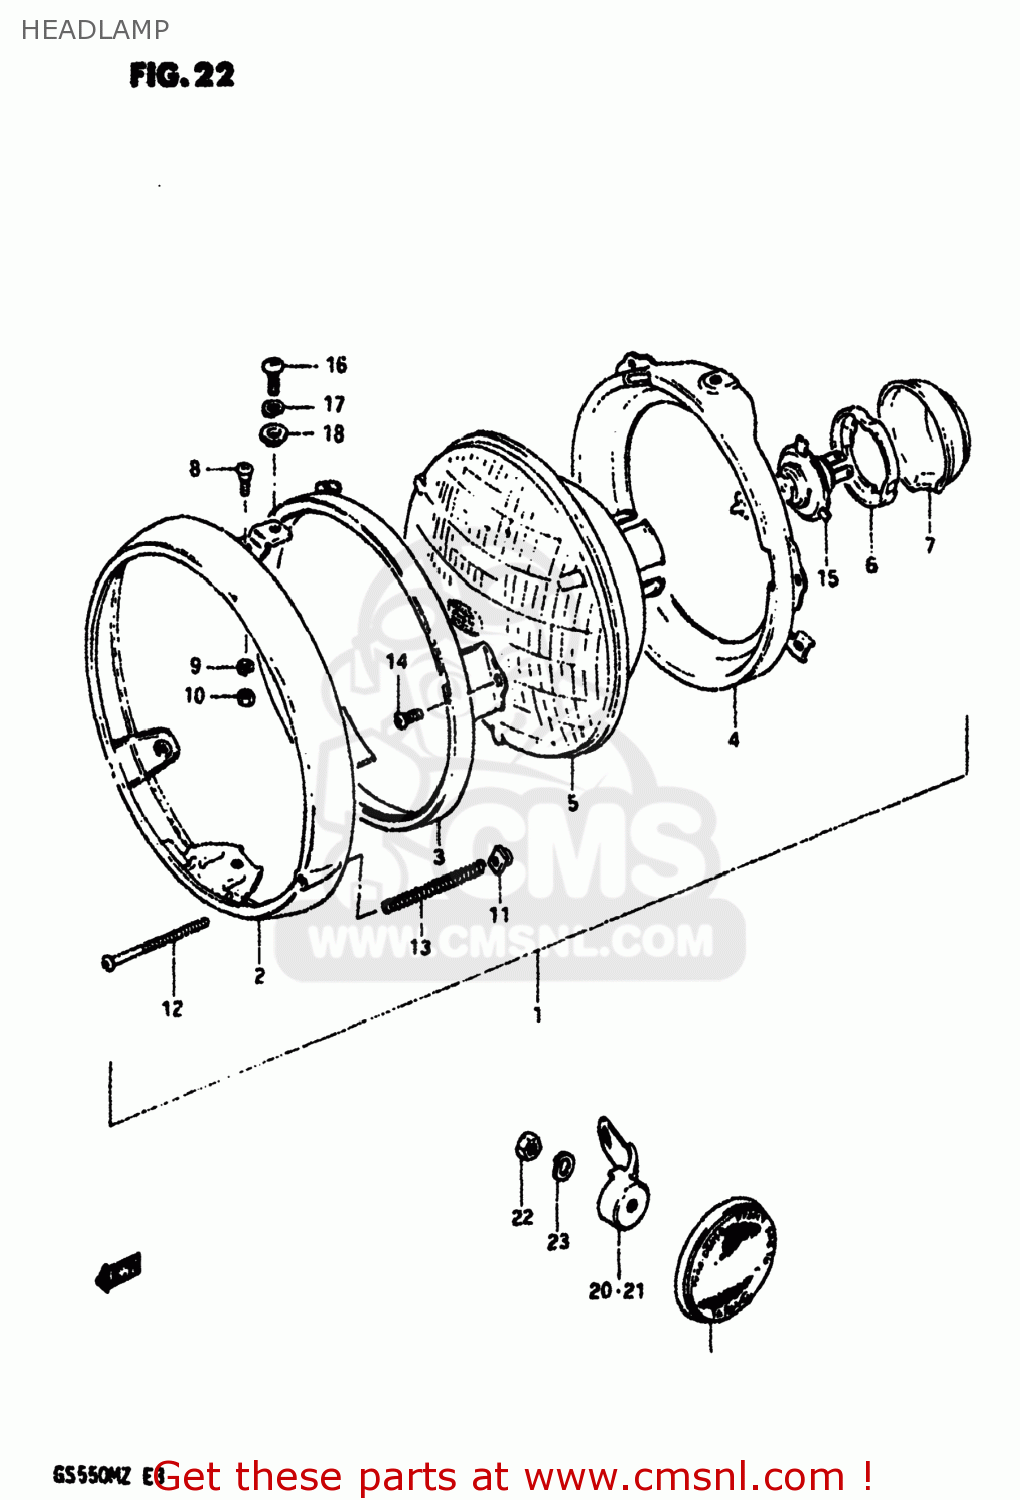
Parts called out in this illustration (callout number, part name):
1	LAMP ASSEMBLY,HEAD
2	RIM,HEADLAMP
3	RETAINING RING
4	RING
5	LAMP UNIT
6	SETTING,BULB
7	COVER,HEADLAMP SOCKET
8	H/LAMP LENS UNIT FITING SCRE
9	LOCK WASHER
10	NUT
11	NUT
12	SCREW,HEADLAMP ADJUST
13	SPRING,ADJUSTING
14	SCREW
15	BULB(12V60/55W,H4)
16	SCREW
17	WASHER,LOCK
18	WASHER
19	REFLEX REFLECTOR,FR
20	BRACKET
21	BRACKET
22	NUT
23	LOCK WASHER
